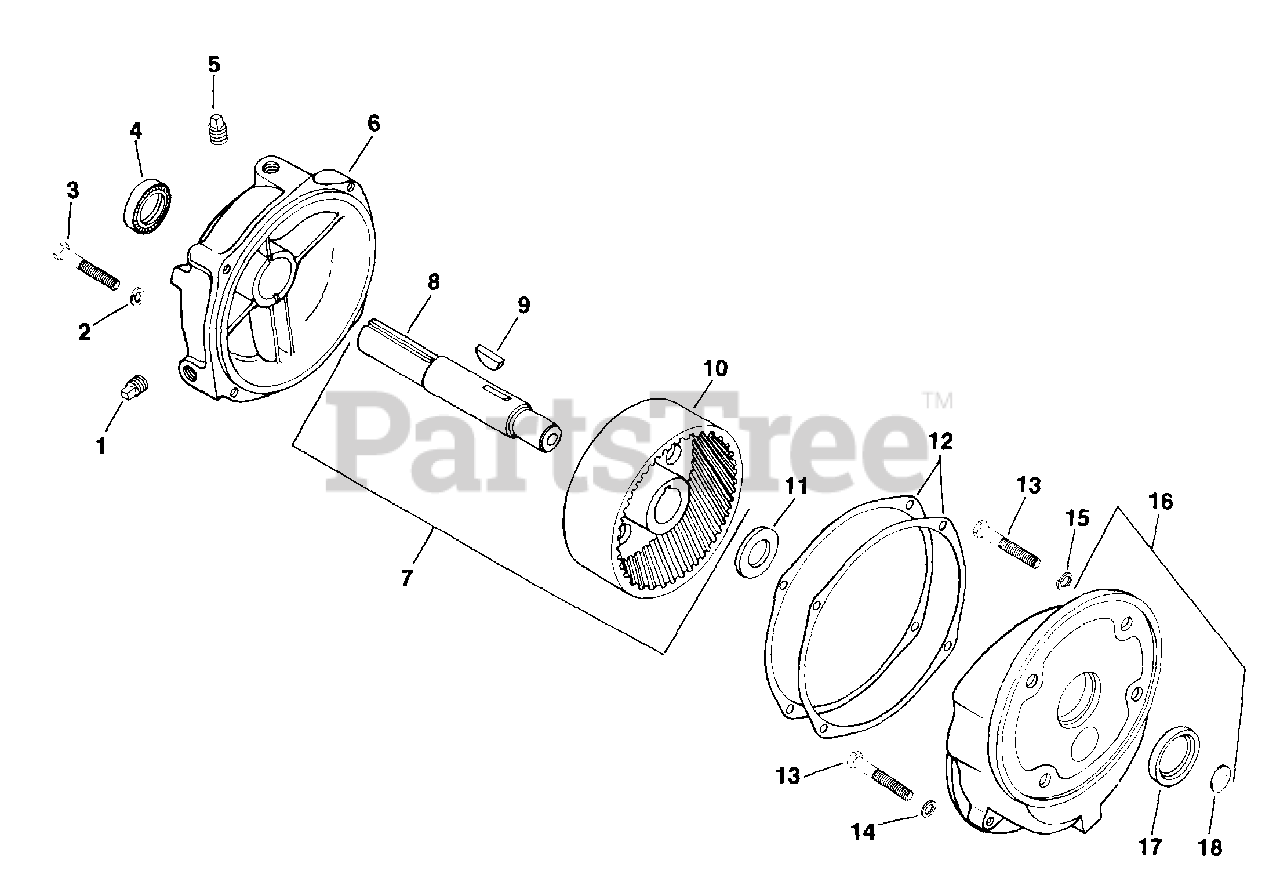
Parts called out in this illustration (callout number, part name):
1	PLUG,PIPE 1/4 NPTF SQUARE HD USE 25 139 53-S
2	WASHER, SPRING LOCK 5/16"
3	SCREW,CAP HD 5/16-18x2"
6	COVER
7	GEAR
8	SHAFT - (#DSC)
9	KEY, 3/16" X 3/4"
10	GEAR - DISCONTINUED
11	BEARING
13	SCREW, CAP HD 3/8-16X7/8"
15	WASHER, SPRING LOCK 3/8"
16	HOUSING - DISCONTINUED
